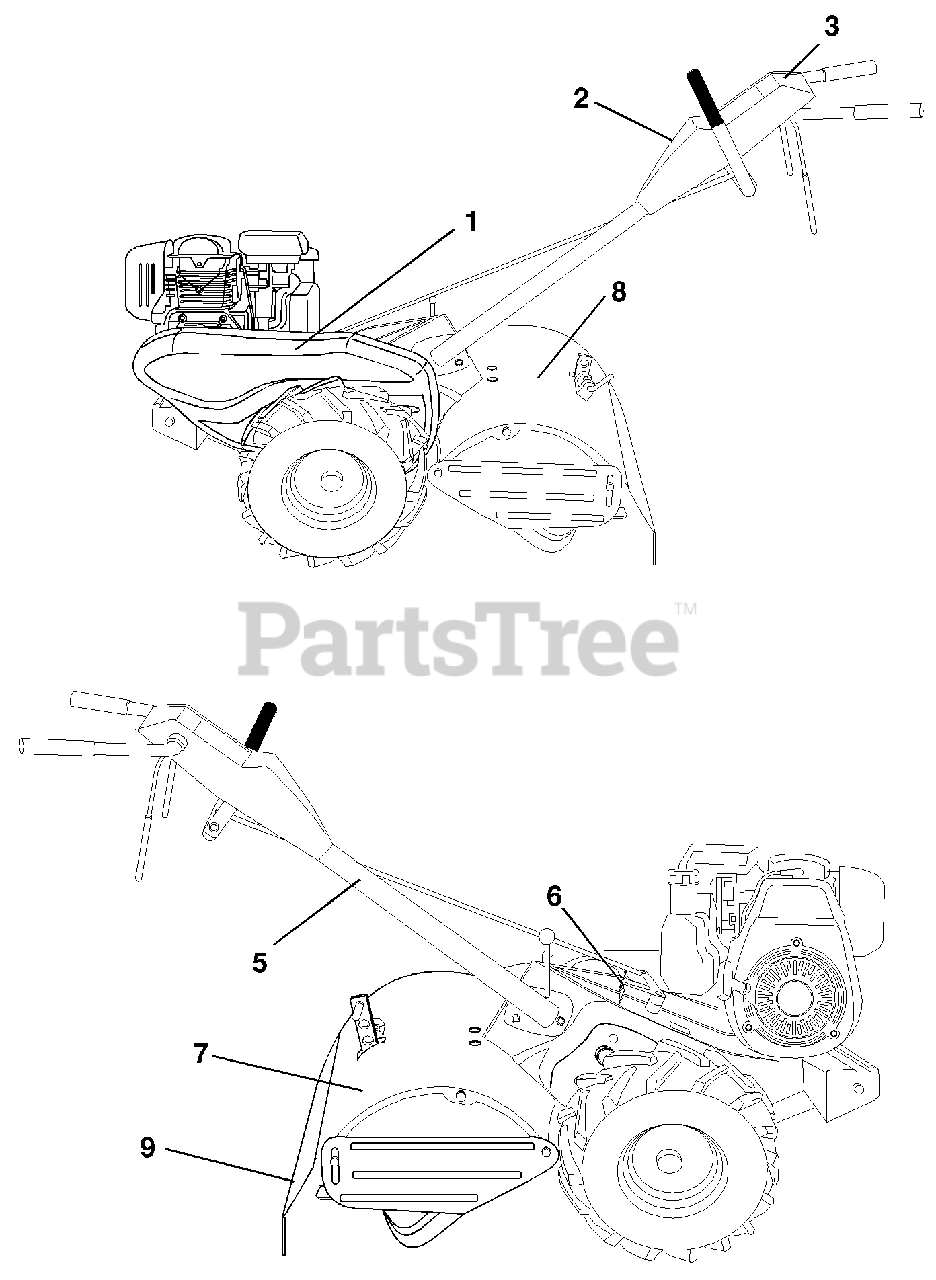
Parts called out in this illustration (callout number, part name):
1	Decal, Blt Grd
2	Decal, Logo
3	Decal, CNTRL PNL
5	Decal, Hand Placement
6	Decal, Shift Indicator
7	Decal, Warning
8	Decal, Tineshield
9	Decal, Warning, Rotating Tines
